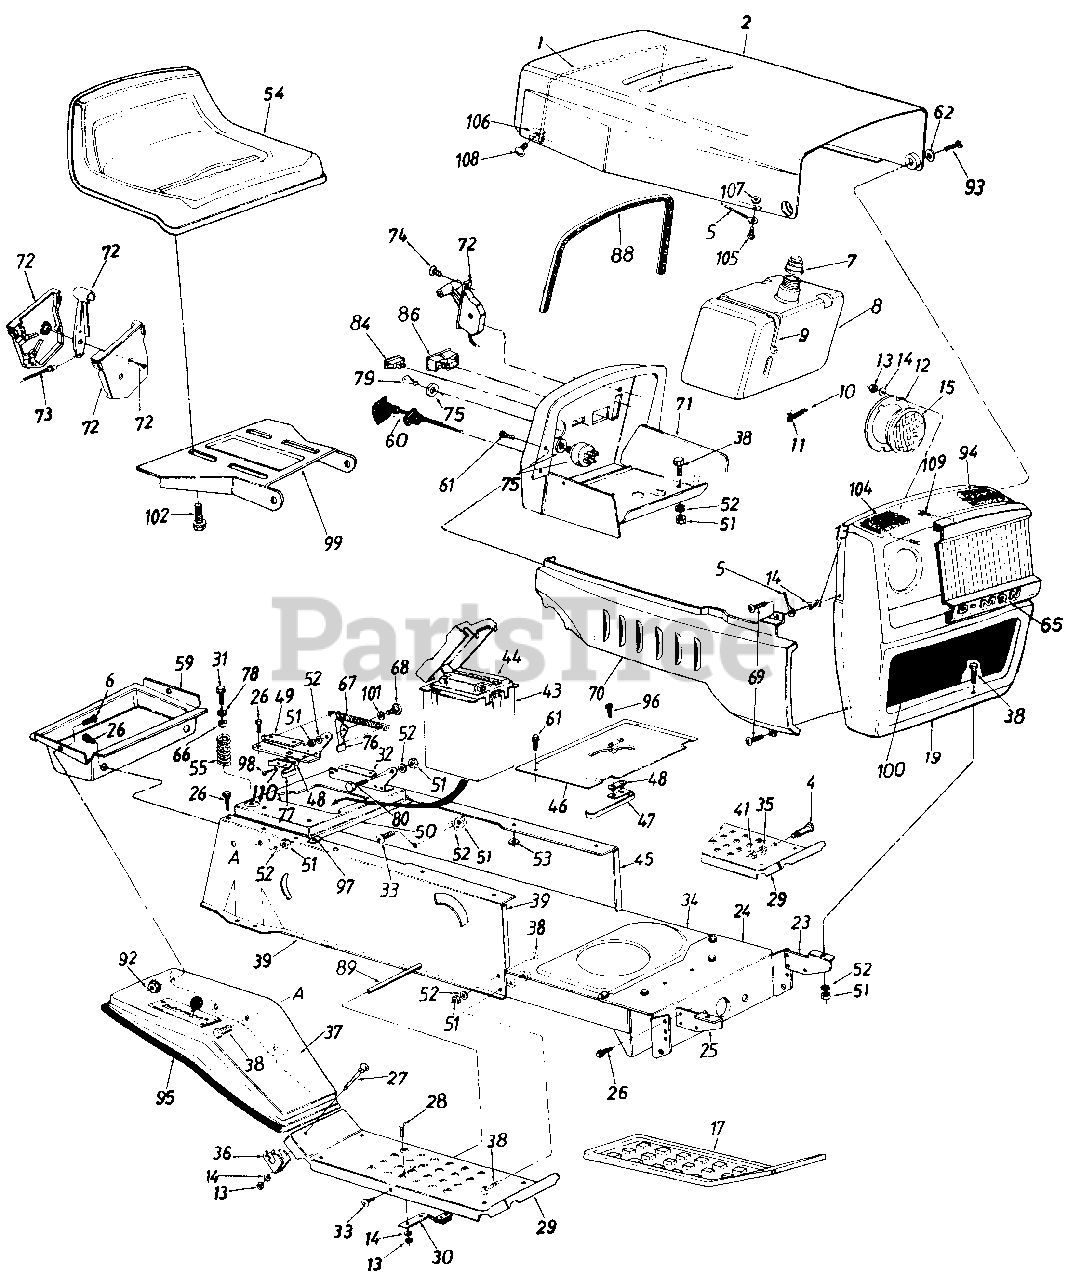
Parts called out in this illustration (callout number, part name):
1	Hood Spring
5	Hood Stop 7" Lg.
6	Truss Hd. Scr. #10-24 x 1/2"
7	Fuel Cap Gauge
8	Fuel Tank
9	Tie Strap
10	Fuel Line
11	Hose Clamp
12	Headlight Retainer
13	Hex Nut 1/4-20 Thd.
14	L-Wash. 1/4" I.D.
15	Headlight
17	Foot Pad L.H.
24	Front Pivot Brkt.
25	Grille Mount Brkt.
26	Hex Wash. Hd. AB-Tap Scr. 5/16 x .75" Lg.
27	Carriage Bolt 1/4-20 x 2.0
28	Carriage Bolt 1/4-20 x .62"
29	Running Board
30	Blade Brake Ass'y.
31	Hex Wash. Hd. Tap Scr. 5/16-18 x 1" Lg.
32	Seat Pivot Brkt. Support L.H.
33	Truss Mach. Scr. 5/16-18 x .75" Lg.
34	Lower Frame
35	L-Wash. 3/8" I.D.
36	FenderClamp
37	Fender
39	R.H. Side Frame
41	Hex Nut 3/8-16 Thd.
43	Battery Box w/Cover
44	12-V Battery
45	L.H. Side Frame
46	Shift Cover
47	Reverse Safety Switch
48	Insulator Nut Plate
49	Seat Pivot Brkt. Support R.H.
50	Hitch Plate
51	Hex Nut 5/16-18 Thd.
52	L-Wash. 5/16" I.D.
53	Ext. L-Wash. 5/16" I.D.
54	Seat Ass'y.
55	Compression Spring
59	Tool Tray
60	Choke Control 29" Lg.
61	Truss Mach. Tap Scr. #10 x .50" Lg.
62	Washer .39" I.D. x .62"
65	Headlight Bezel
66	Bushing
67	Ext. Spring 5.31" Lg.
68	Shld. Bolt .437" Dia. x .268"
69	Truss Hd. Scr. 1/4-20 x .75"
70	R.H. Grille Side Panel
71	Dash Panel Ass'y.
72	Throttle Control Box Ass'y.
73	Throttle Control Wire
74	Truss Mach. AB-Tap Scr.
75	Ignition Switch
76	Seat Lift Bracket
77	Spring Switch
78	Fl-Wash. .344" I.D.
79	Ignition Key
80	Shld. Bolt .437" Dia. x .162"
84	Light Switch
86	Ammeter
88	Molding Strip 27" Lg.
89	Running Board Rod
92	Hex Sems Nut #10-24 Thd.
93	Shld. Bolt .375" Dia. x .125
94	L-Nut 1/4-28 Thd.
95	Trim Strip 31" Lg.
96	Hex Wash. Hd. AB-Tap Scr. #8 x .50" Lg.
97	Speed Nut #10Z
98	Hex Wash. AB-Tap Scr. #8 x .5" Lg.
99	Seat Pivot Brkt.
100	Grille Screen
101	Spr-Wash. .445" I.D. x 75" O.D.
102	Hex Hd. Tap Scr. 3/8-16 x .75" Lg.
104	Foam Strip 818" x 1-1/8" x 1-1/2"
105	Pop Rivet
106	Hood Spring Retainer
107	Fl-Wash.
108	Oval Hd. Screw
109	Hex Tap Screw
110	Fiber Washer
